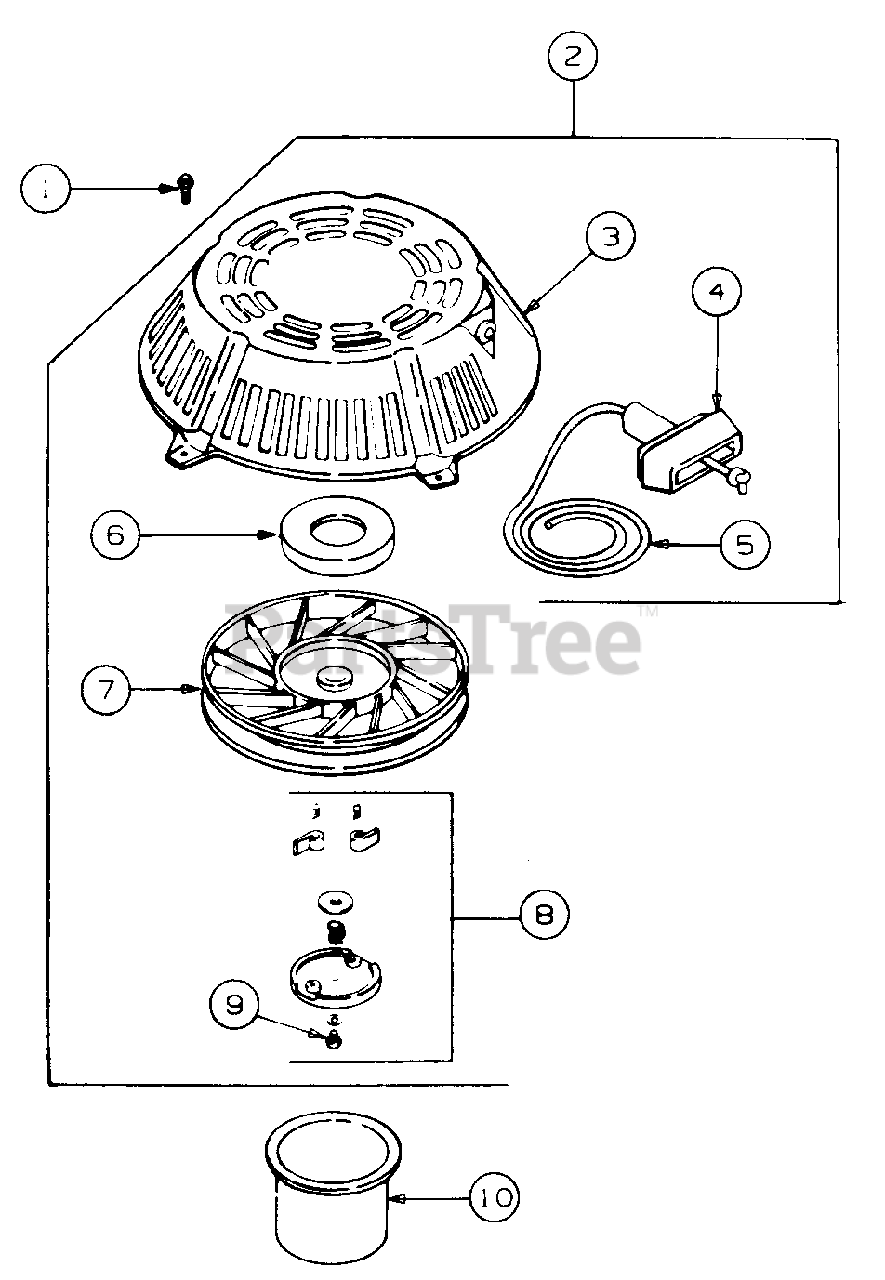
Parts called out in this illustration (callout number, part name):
1	Screw, M5 X 0.8 X 10
2	Starter, Retractable Assy
3	Housing, Starter
4	Handle, Recoil Start
5	Rope, Starter
6	Spring & Keeper
8	Kit, Pawl (Dog)
9	Screw, Pozidriv
